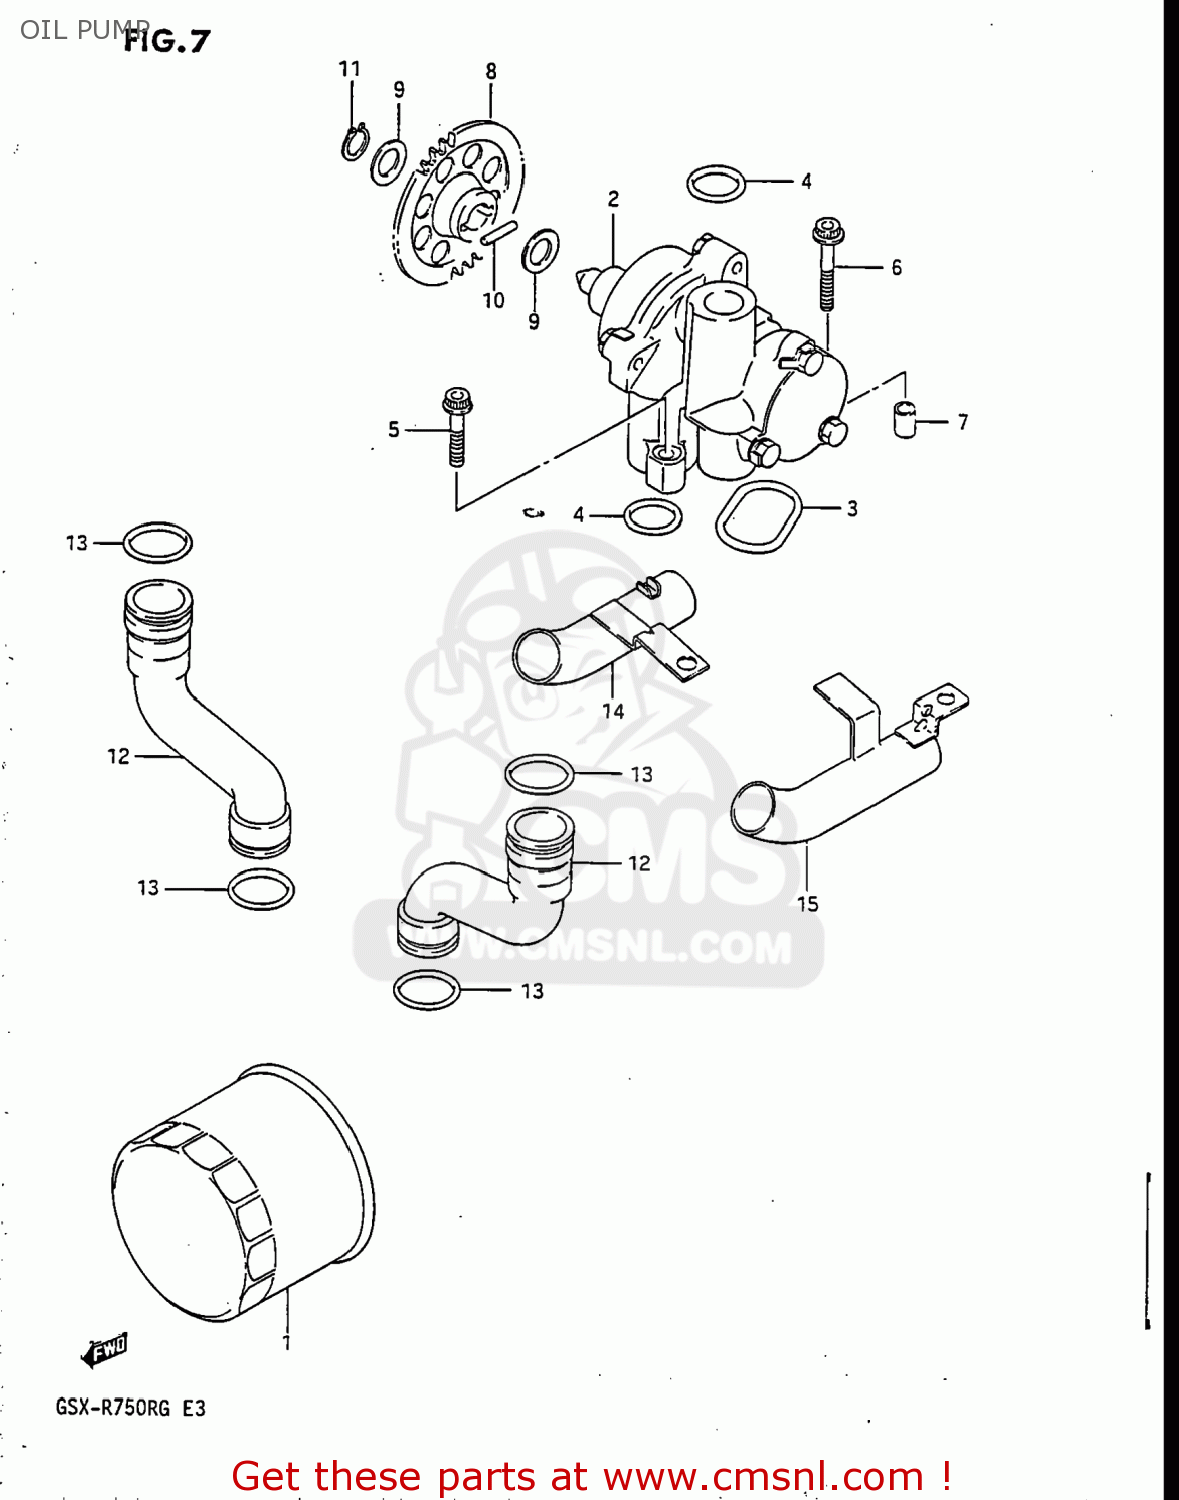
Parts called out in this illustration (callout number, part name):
1	FILTER ASSY,ENGINE OIL
2	PUMP ASSEMBLY,OIL
3	O RING,OIL PUMP
4	O RING(D:3.2,ID:17.8)
5	BOLT
6	BOLT
7	PIN
8	GEAR,OIL PUMP DRIVEN
9	SHIM
10	PIN(5X18)
11	CIRCLIP
12	HOSE,OIL
13	O-RING
14	PIPE,OIL,OUTLET,UNDER
15	PIPE,OIL,OUTLET,UNDER
